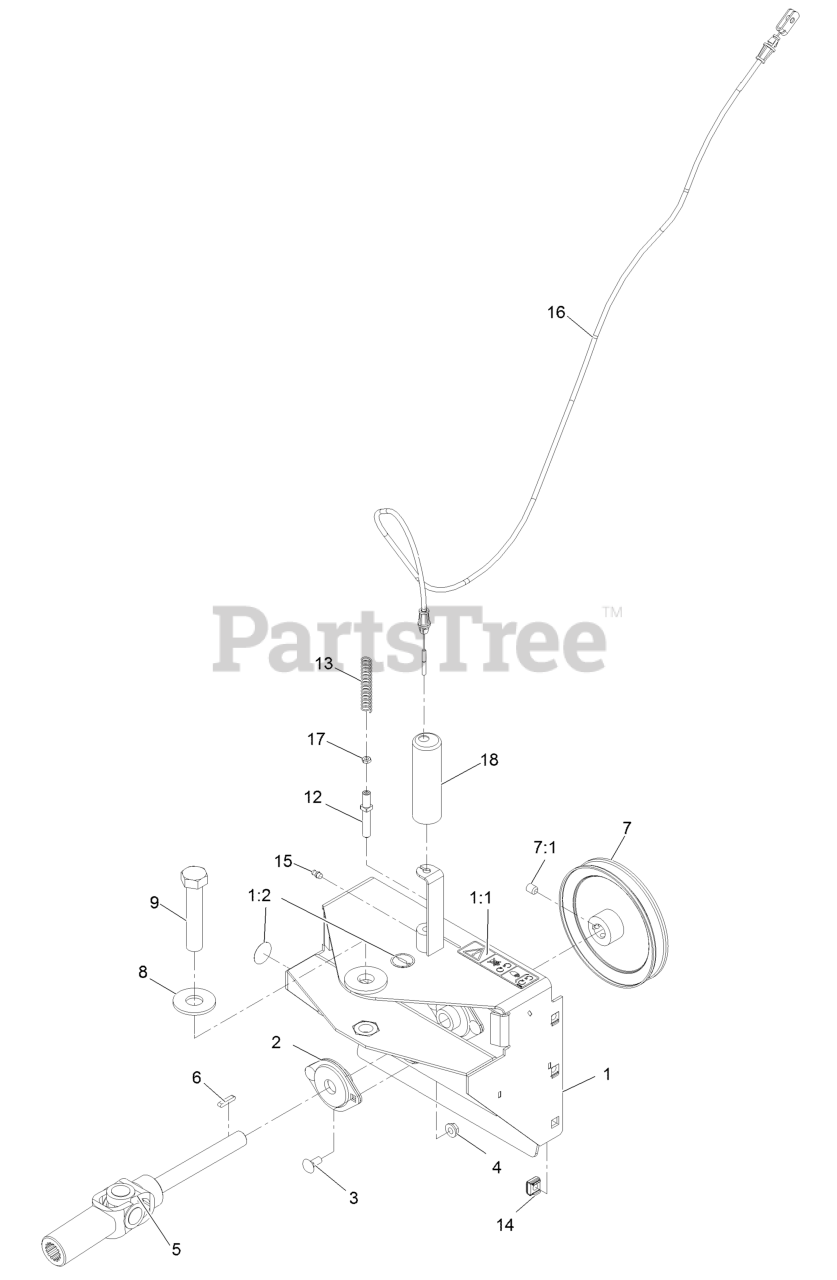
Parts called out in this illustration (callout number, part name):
1	Broom Mounting Frame ASM
1:1	Decal-Cover, Missing
1:2	Decal-Grease
2	Bearing-Shaft
3	Bolt-Carriage 5/16-18 X 3/4
4	Nut-Whizlock 5/16-18
5	Shaft-Drive
6	Key-Round End
7	Pulley-Impeller
7:1	Setscrew-5/16-18 X 3/8
8	Washer
9	Screw-HH 3/4-16 X 3 3/4
12	Pin-Swing
13	Spring-Compression
14	Nut-Retainer
15	Zerk-1/4-28 Str
16	Cable-Angle, Broom
17	Nut-Hex
